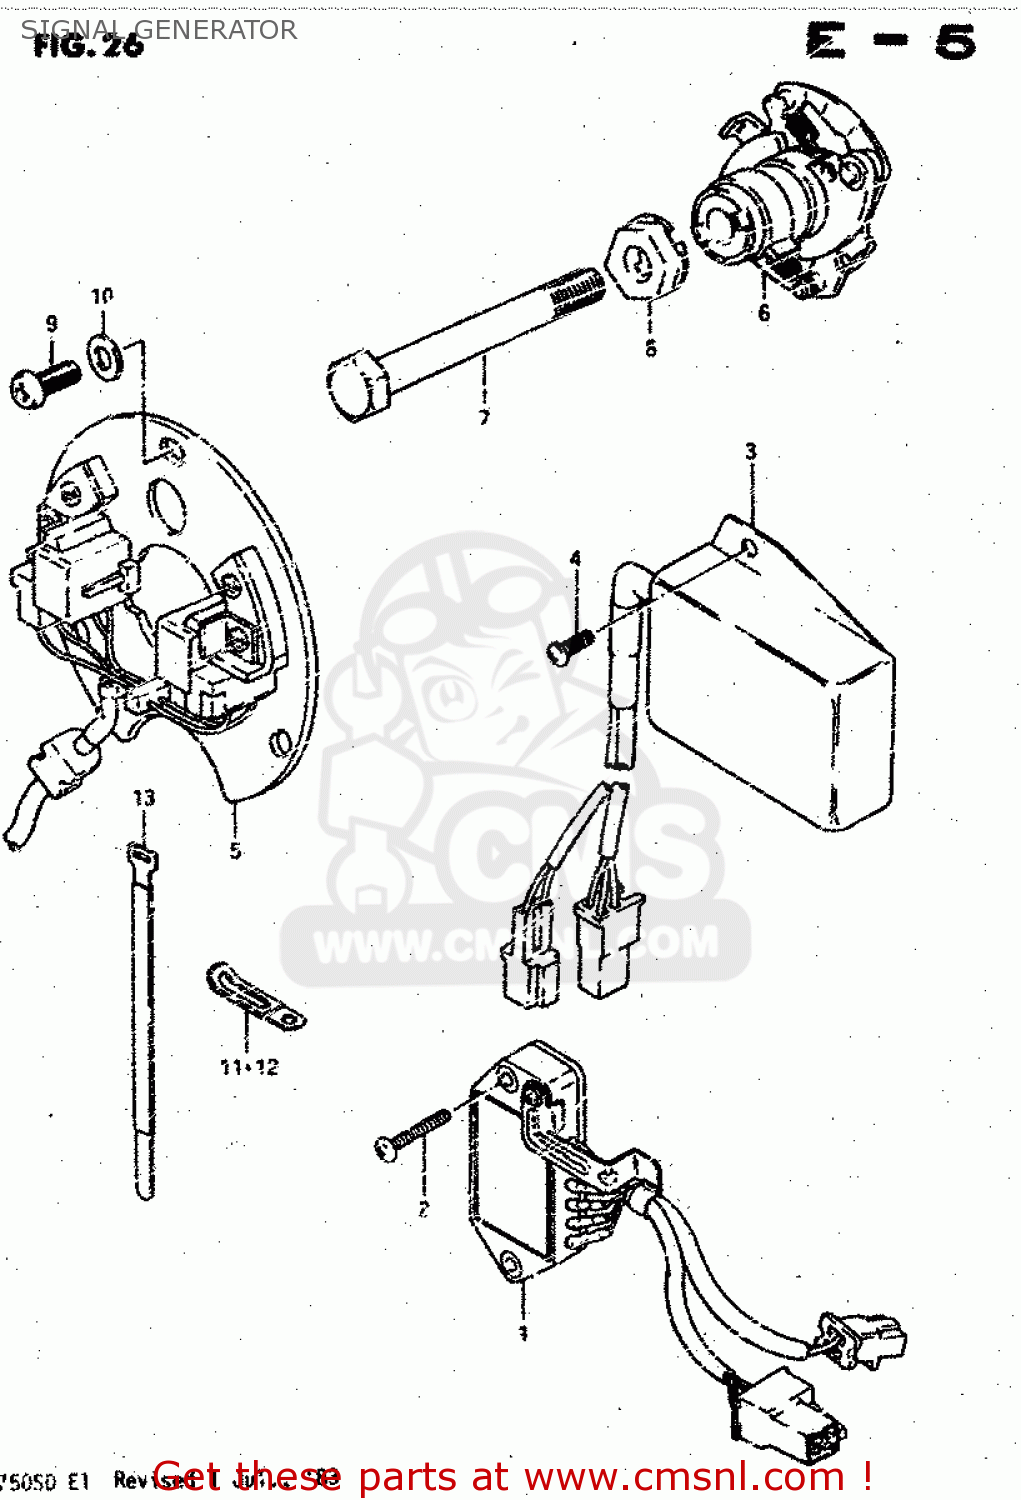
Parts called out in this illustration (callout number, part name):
1	IGNITER UNIT
2	SCREW
3	IGNITOR UNIT
4	SCREW
5	SIGNAL GENERATOR ASSEMBLY
6	GOVERNOR ASSEMBLY
7	BOLT
8	WASHER
9	SCREW(5X12)
10	WASHER
11	CLAMP L:35
12	CLAMP
13	CLAMP
